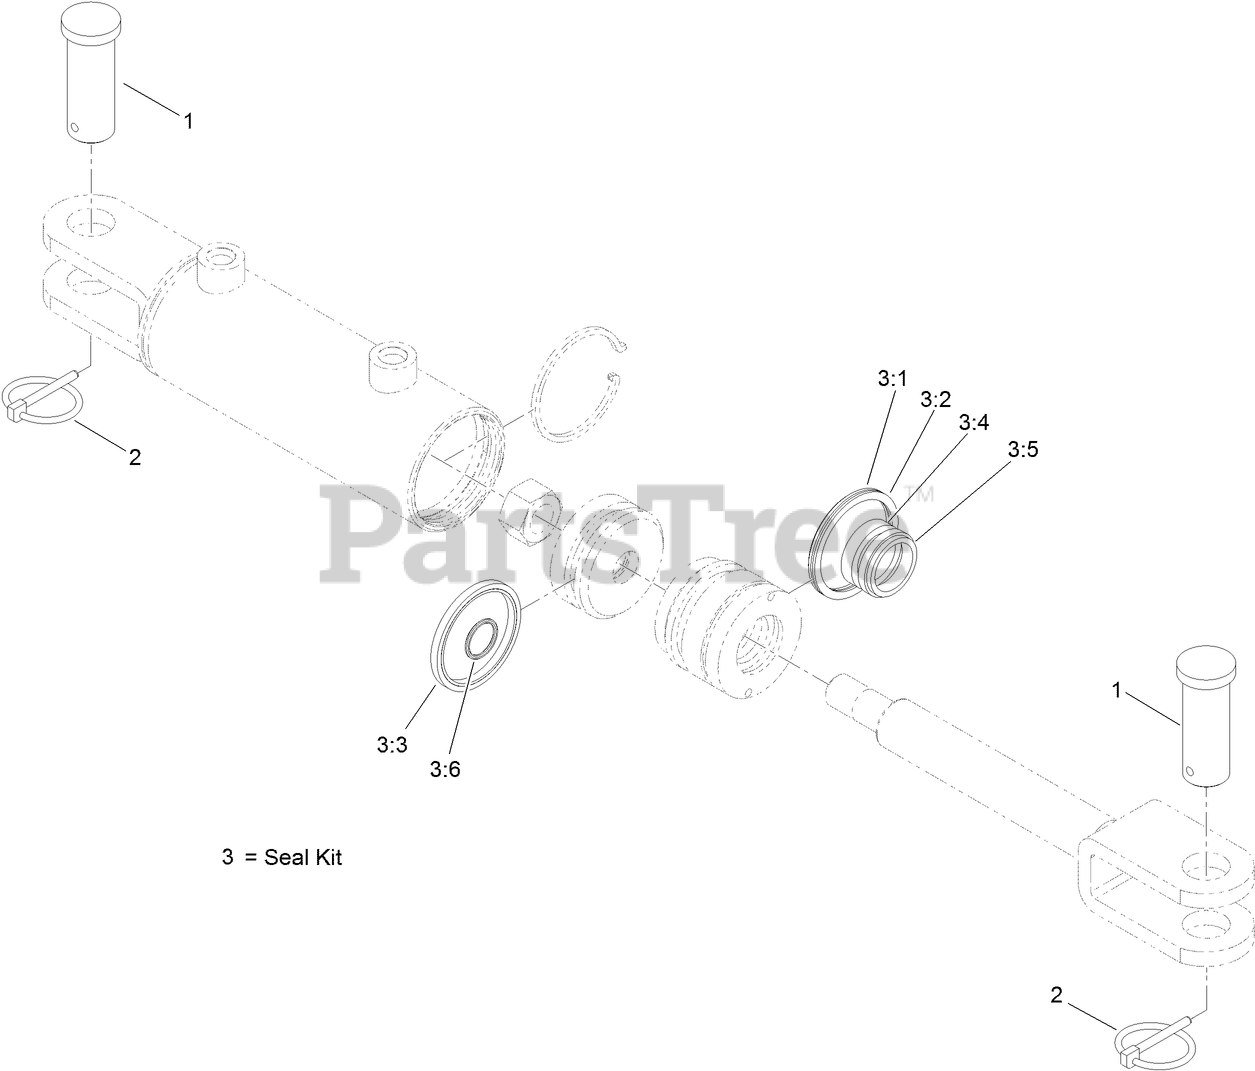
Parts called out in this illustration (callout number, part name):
1	PIN-CLEVIS
2	PIN-LYNCH
3	SEAL KIT
3:1	O-RING
3:2	BACKUP RING
3:3	Psp Seal
3:4	BS SEAL
3:5	Dust Seal
3:6	O-RING
